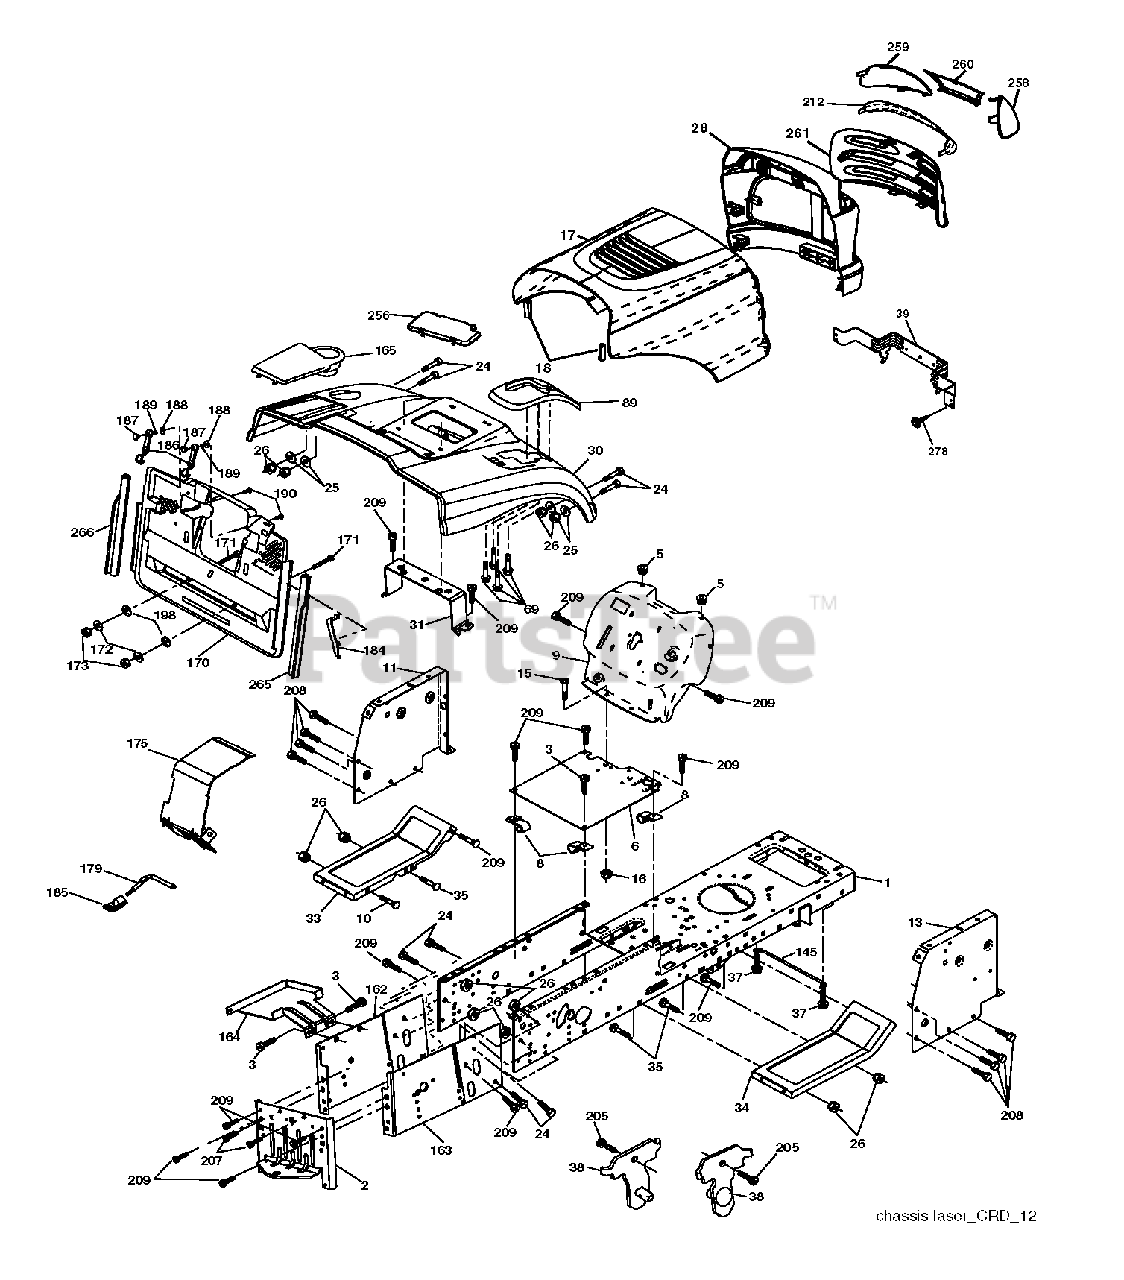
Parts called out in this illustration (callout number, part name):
1	CHASSIS
3	SCREW 3/8-16X3/4
5	BUMPER.RUBBER.HOOD
8	CLIP,INSULATOR
9	FENDER LT SH
10	BOLT D
11	PANEL.DASH.LH.LTX
13	PANEL DASH RH
16	NUT
18	BUMPER.HOOD.LARGE.1.75"
24	BOLT
25	WASHER
26	NUT
28	GRILLE.LASER II.DUAL.
30	FENDER.PNT.CRD.MS428 K
31	BRACKET SUPPORT FENDER
35	BOLT
37	SCREW LT
39	BRACKET PIVOT
69	SCREW.HI-LO.CONSOLE
145	ROD.PIVOT.HOOD
164	SUPPORT
165	FENDER.PNT.CRD.
171	BOLT
172	WASHER
184	BRACKET.ACTUATOR.BAGGER.SRD
186	LATCH ASSY
187	WELDNUT
190	SCREW
205	SCREW LT
207	SCREW, 5/16-18 X 1/2
208	SCREW 3/8-16X1/2
209	SCREW, 3/8-16X3/4
256	FENDER.PNT.CRD
258	LENS.LASER.2PC.LH.CLEAR.SVC
259	COVER.LENS.LASER.II
278	SCREW.#10 X 0.750.BOS THREAD
